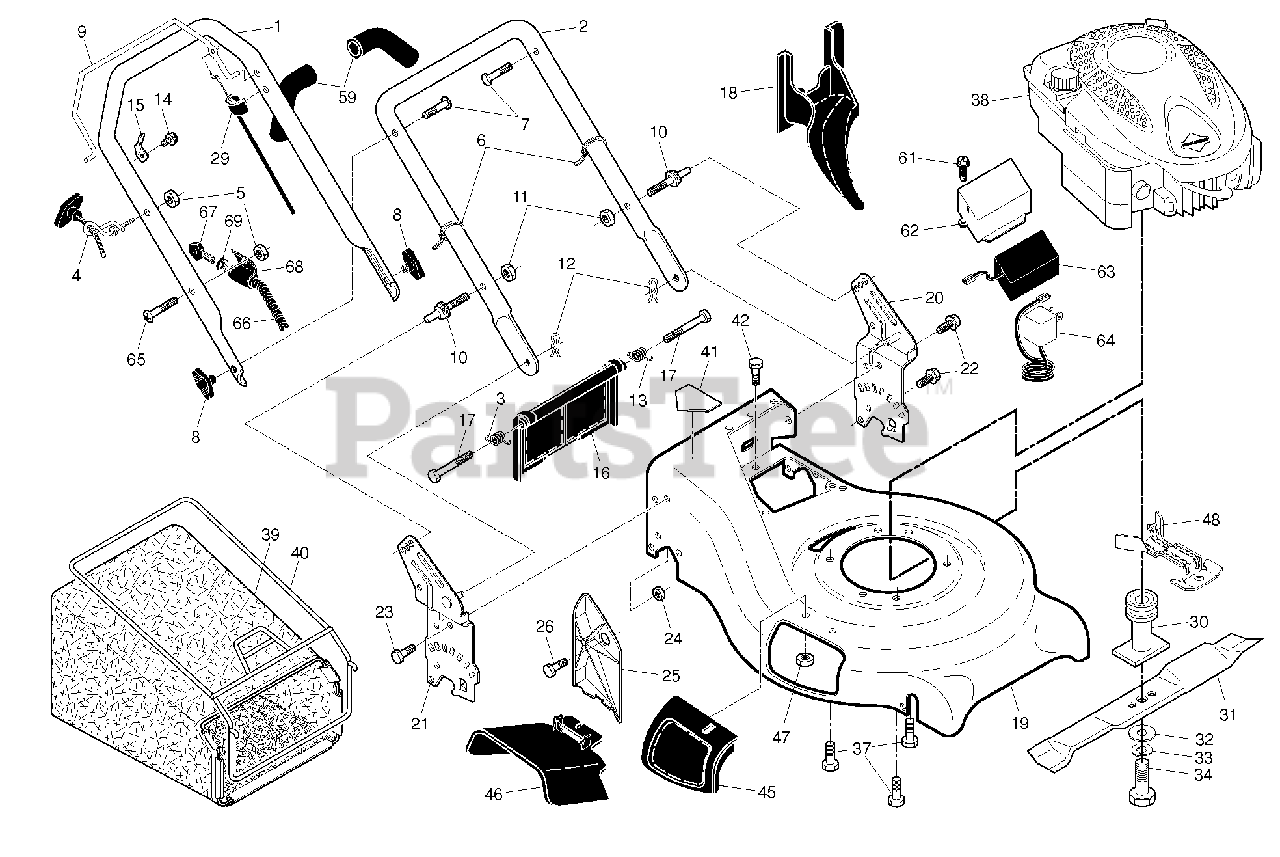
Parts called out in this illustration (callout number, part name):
2	HANDLE LOWER
3	SPRING.RH.REAR.DOOR.21.RWGD
4	GUIDE.ROPE.STD.BLK.ZIN
5	NUT
6	TIE GUIDE
7	BOLT, HANDLE 5/16-18X1.75
8	KNOB, DEFLECTOR
11	NUT, LOCK 5/16-18
12	HAIRPIN COTTER
13	SPRING.LH.REAR.DOOR.21.RWGD
15	BRACKET.UPSTOP.RT
16	REAR DOOR ASSEMBLY
18	PLUG.MULCHER.RGD.21.
20	BRKT.ASM HNDL
21	BRKT.ASM.HNDL
22	BOLT.HEX.HD.WASHER.5/16-18X.75
23	BOLT, HEX HEAD 5/16-18
24	NUT.71038.31-18.HEX.NYLOCK
25	CLIPPING DEFLECTOR
29	CABLE.MZR.47.75.SNAP-IN.PU.L
30	ADAPTER.BLADE/PULLEY.25M
31	BLADE.21.PUSH
32	WASHER,HARDEN
33	LOCKWASHER
34	SCREW, HEX HD 3/8-24 X 1-3/8
37	BOLT 3/8-16X1-1/8
40	FRAME.GBAG.21.RWGD.SC
41	DECAL.INTERNATIONL.CUTFINGER
48	BRACKET.ENG/BELTKEEPER.BZP
59	GRIP.HANDLE.FOAM.WIDE.(1 SIDE)
63	BATTERY.AMP.CONNECTOR
65	SCREW.(COMBINATION CONTROL)
67	KEY.MOLDED
68	HOUSING.WIRING.HARNESS
69	NUT.CAP.SNAP-ON.KEY START
